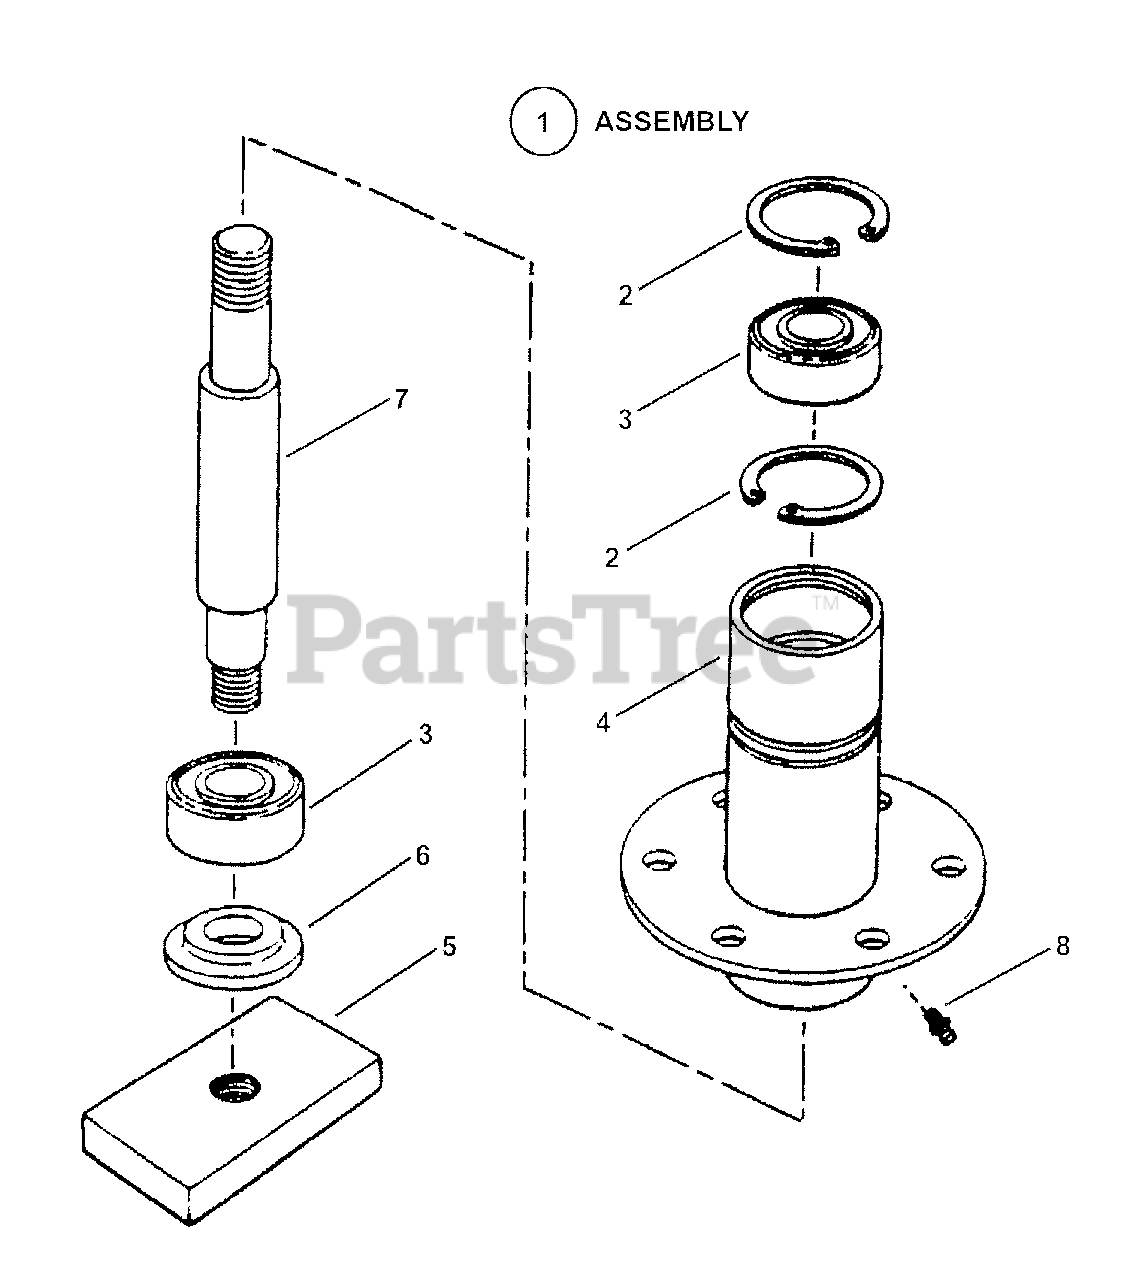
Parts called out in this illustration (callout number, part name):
1	ASSEMBLY, 42" Spindle
2	RING, 1-3/4" External Retaining Ring
3	BALL BEARING, 3/4" I.D.
4	WELDMENT, Spindle Housing
5	HOLDER, Blade
6	WASHER, Spindle
7	SHAFT, Blade Spindle (3.47 shank length)
8	FITTING, Lube, Press-In (for .187 dia. Hole)
